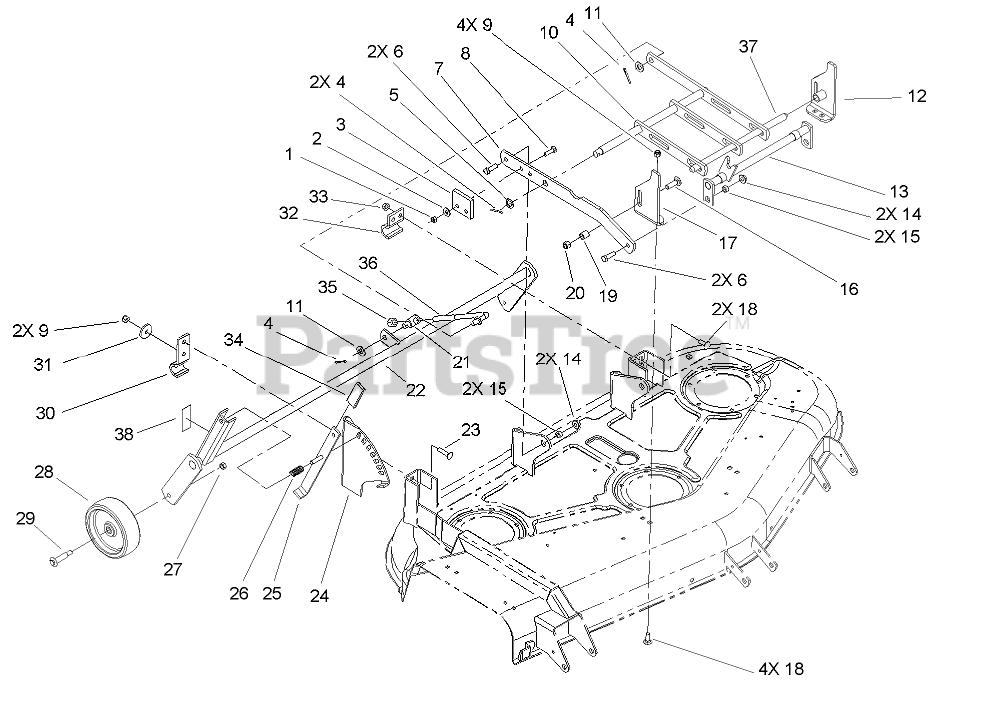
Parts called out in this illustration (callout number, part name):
1	NUT-LOCK, NI
2	WASHER-FLAT
3	BUMPER
4	PIN-COTTER
5	WASHER-FLAT
6	SCREW-HH
7	BAR-DRAFT
8	SCREW-CARR
9	NUT-LOCK, NI
10	BAR-LEVELER
11	WASHER-FLAT
12	LH BRACKET ASM
13	HITCH ASM
14	LOCKNUT-FLANGE
15	SPACER
16	BOLT-CARR
17	RH BRACKET ASM
18	BOLT-CARR
19	SPACER
20	NUT-LOCK, NI
21	TRUNNION
22	WHEEL SUPPORT ASM
23	SCREW-CARR
24	QUADRANT
25	LEVER-HOC
26	SPRING-COMPRESSION
27	NUT-HEX
28	WHEEL
29	BOLT-SHOULDER
30	BRACKET-PIVOT
31	WASHER-SUPPORT
33	NUT-FLANGE
35	NUT-LOCK, NI
36	ROD-ADJUSTING
37	Shaft-Front
38	DECAL-HOC
